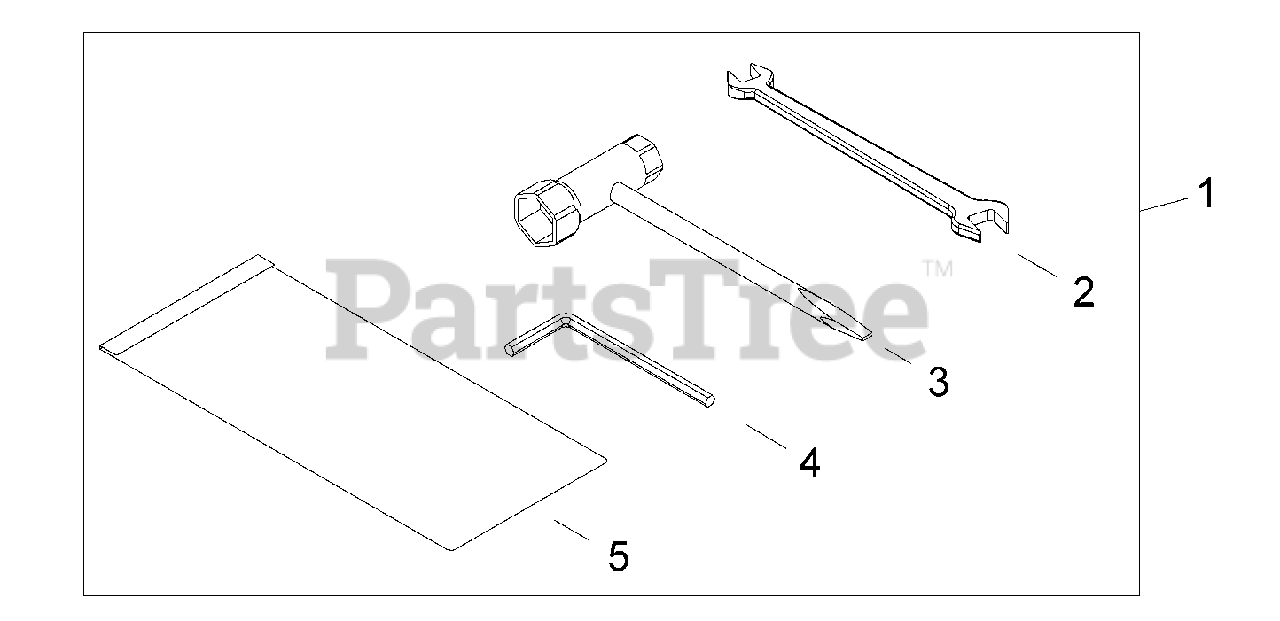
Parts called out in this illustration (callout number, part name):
1	TOOL KIT
2	SPANNER - 8X10mm
3	T-WRENCH - 13X16mm
4	HEX KEY - 4mm
5	BAG, TOOL
